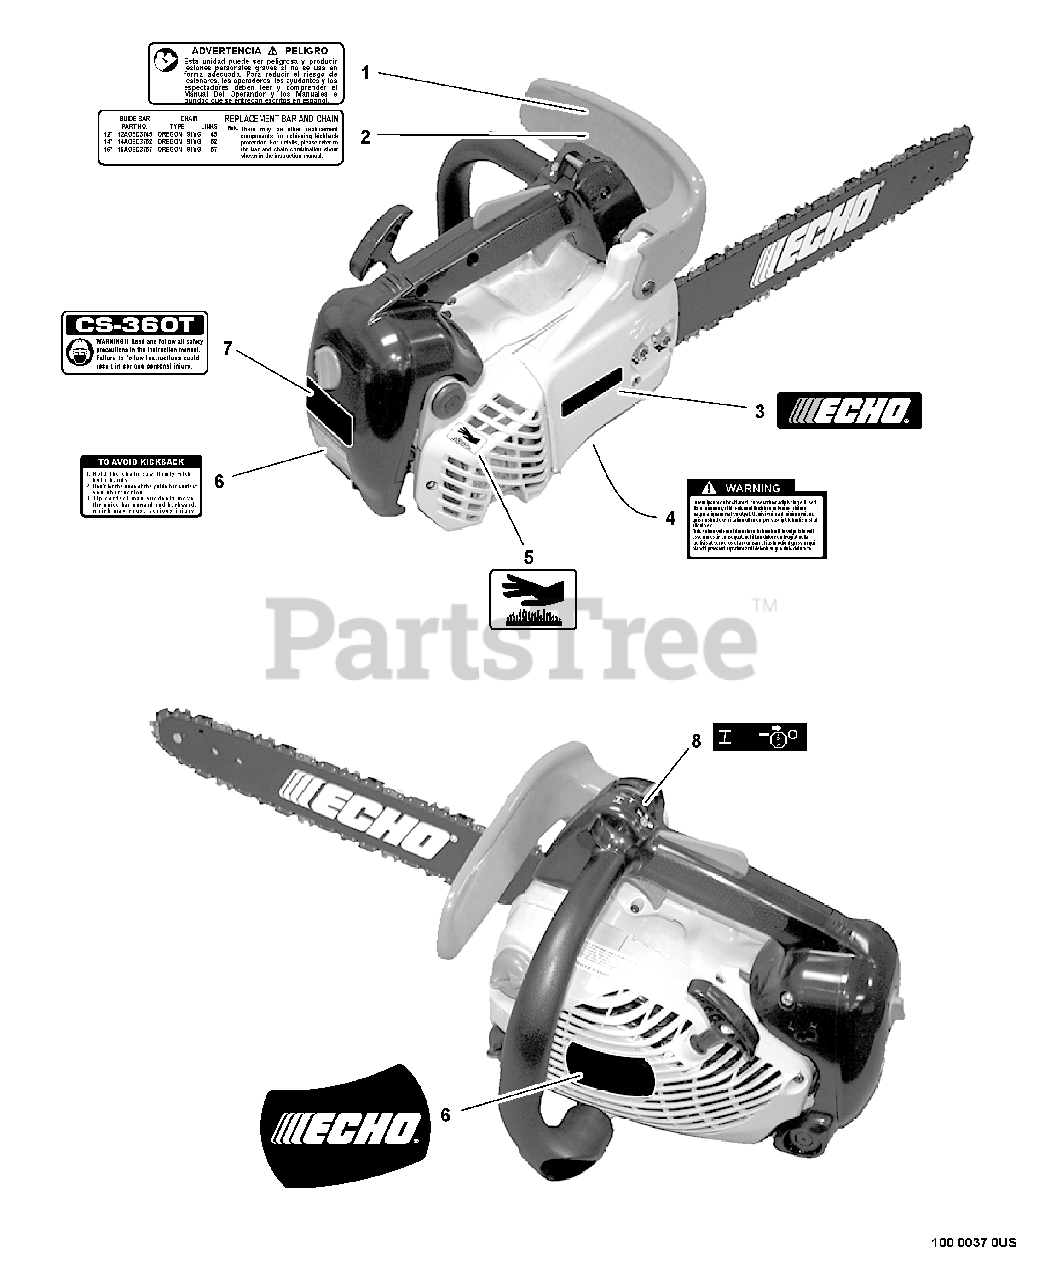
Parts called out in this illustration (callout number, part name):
1	LABEL - CAUTION -- SPANISH
2	LABEL - BAR & CHAIN
3	LABEL - ECHO
4	LABEL - WARNING
5	LABEL - HOT SURFACE
6	LABEL - KICK BACK
7	LABEL - MODEL CS-360T
8	LABEL - STOP
9	LABEL - ECHO
